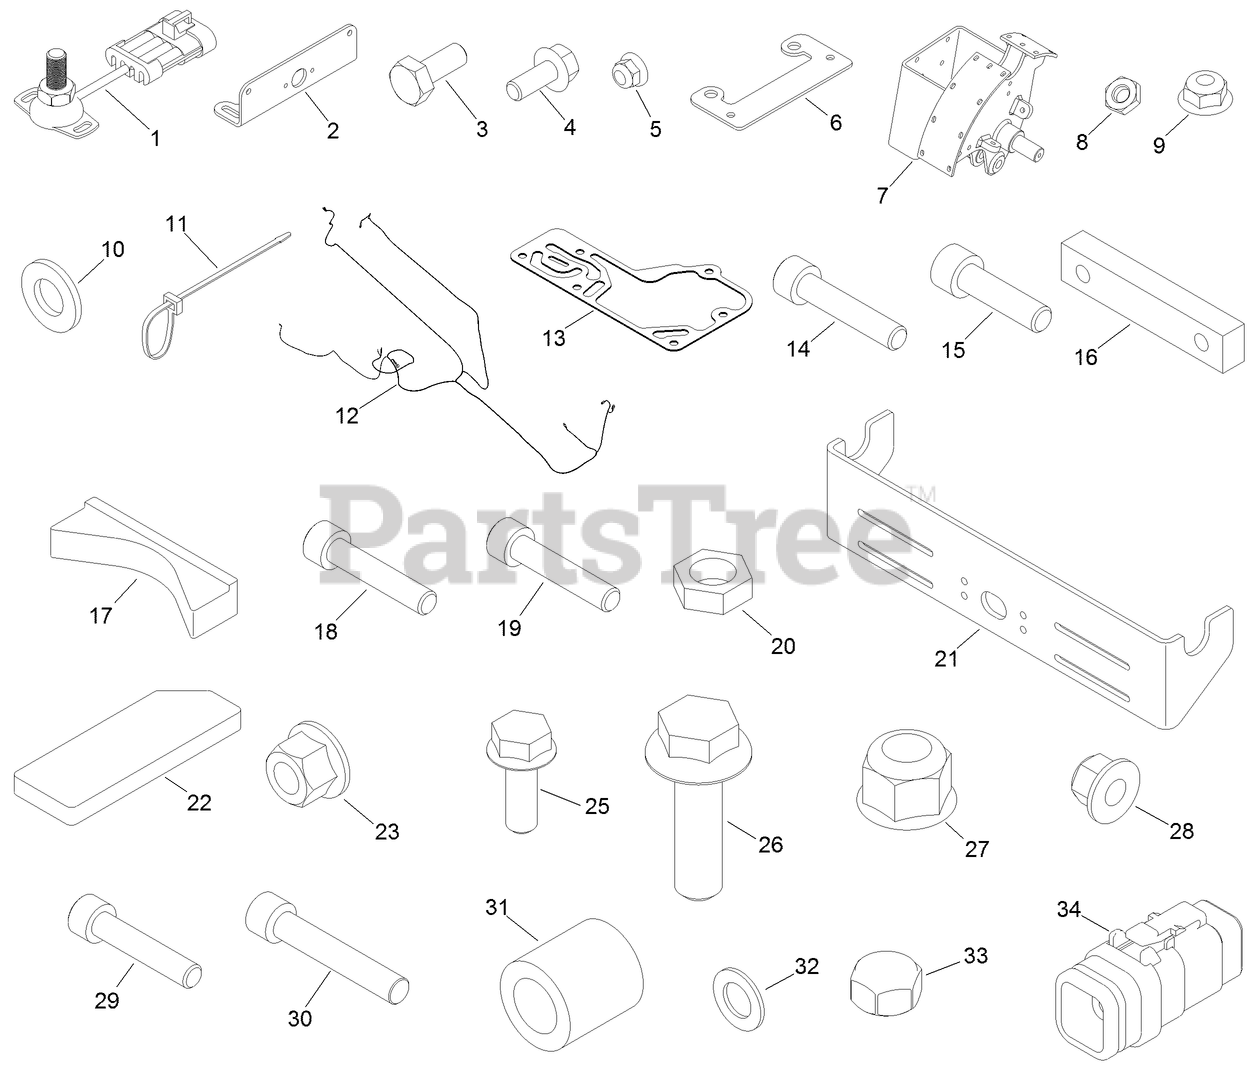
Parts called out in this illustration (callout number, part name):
1	SENSOR-ROTARY
2	BRACKET-SENSOR, ROTARY
3	SCREW-HH
4	SCREW-HHF
5	NUT-LOCK, HHF
7	UPPER CAM ASM
8	NUT-HEX
9	NUT-HHF
10	WASHER-FLAT
11	TIE-CABLE
14	SCREW-HSH
15	SCREW-HSH
16	BLOCK-ADJUSTMENT
17	BRACE-MOTOR, FLOATING
18	SCREW-HSH
19	SCREW-HSH
20	NUT-JAM
21	PLATE-MOUNT, SWITCH
22	PLATE-FLAG
23	NUT-FLANGE, NI
25	SCREW-HHF
26	SCREW-HHF
27	NUT-LOCK, NI
28	NUT-HF
29	SCREW-HSBH
30	SCREW-HSH
31	SPACER
32	WASHER
33	CAP-VALVE, ALUMINUM
